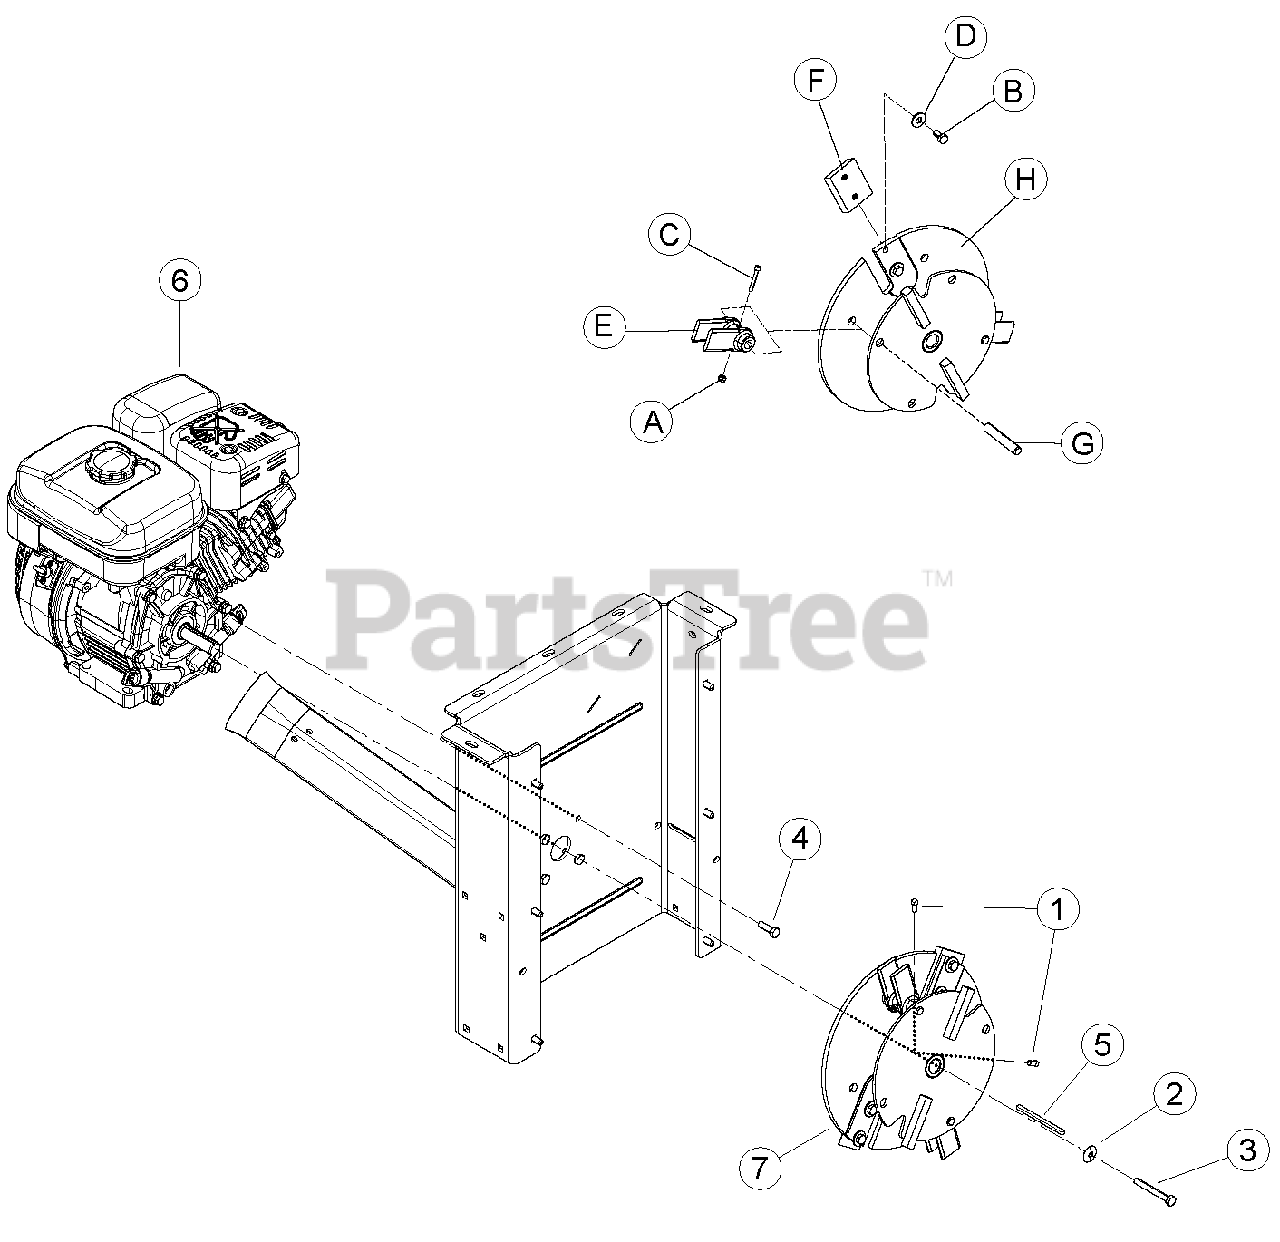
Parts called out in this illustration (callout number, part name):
1	SCREW, 1/4 X 1/2 SQ HD CP SET
2	WASHER, 5/16 GR8 USS FLAT
3	BOLT, 5/16 X 2-1/2 HEX NF GR5 ZP
4	BOLT, 5/16-24 X 1 HEX GR5 ZP
5	KEY, 3/16 SQUARE X 3.38 LONG
6	ENGINE, SUBARU 170CC SP170 (FOR SERVICE SEE ENGINE OWNER'S MANUAL OR YOUR NEAREST UTHORIZED SUBARU ENGINE DEALER)
7	ASSEMBLY, S/C ROTOR (REPLACED AND SUPERSEDED. FOR SERVICE ORDER KIT # 77615-00, ROTOR SSEMBLY WITH KNIVES)
A	NUT, #10/24 NYLOCK TYPE NM, ZP
B	BOLT, 5/16-18 X 5/8 GR8 HCS PATCH Z
C	SCREW, #10-24 X 1-3/8 SKT HD CAP PL
D	WASHER, 5/16 FLAT GR8 USS
G	SHAFT, SHREDDER
H	WELDMENT, S/C ROTOR
